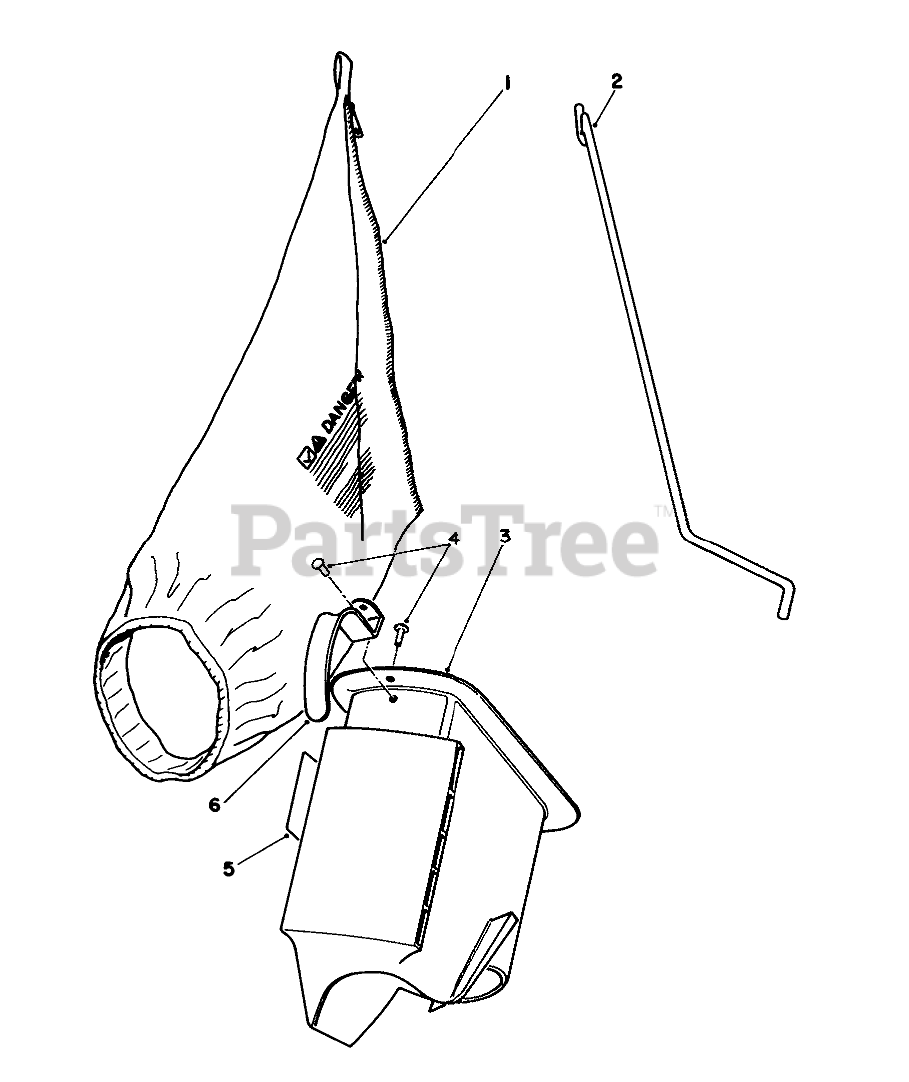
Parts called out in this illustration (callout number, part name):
1	BAG REPLACMNT44-0540
2	BAG ROD
3	Grass Chute (Incl. Ref. #4 & 6)
4	RIVET 3/16 X 7/16
5	BAG CHUTE DECAL
6	HANDLE-GRASS CHUTE
